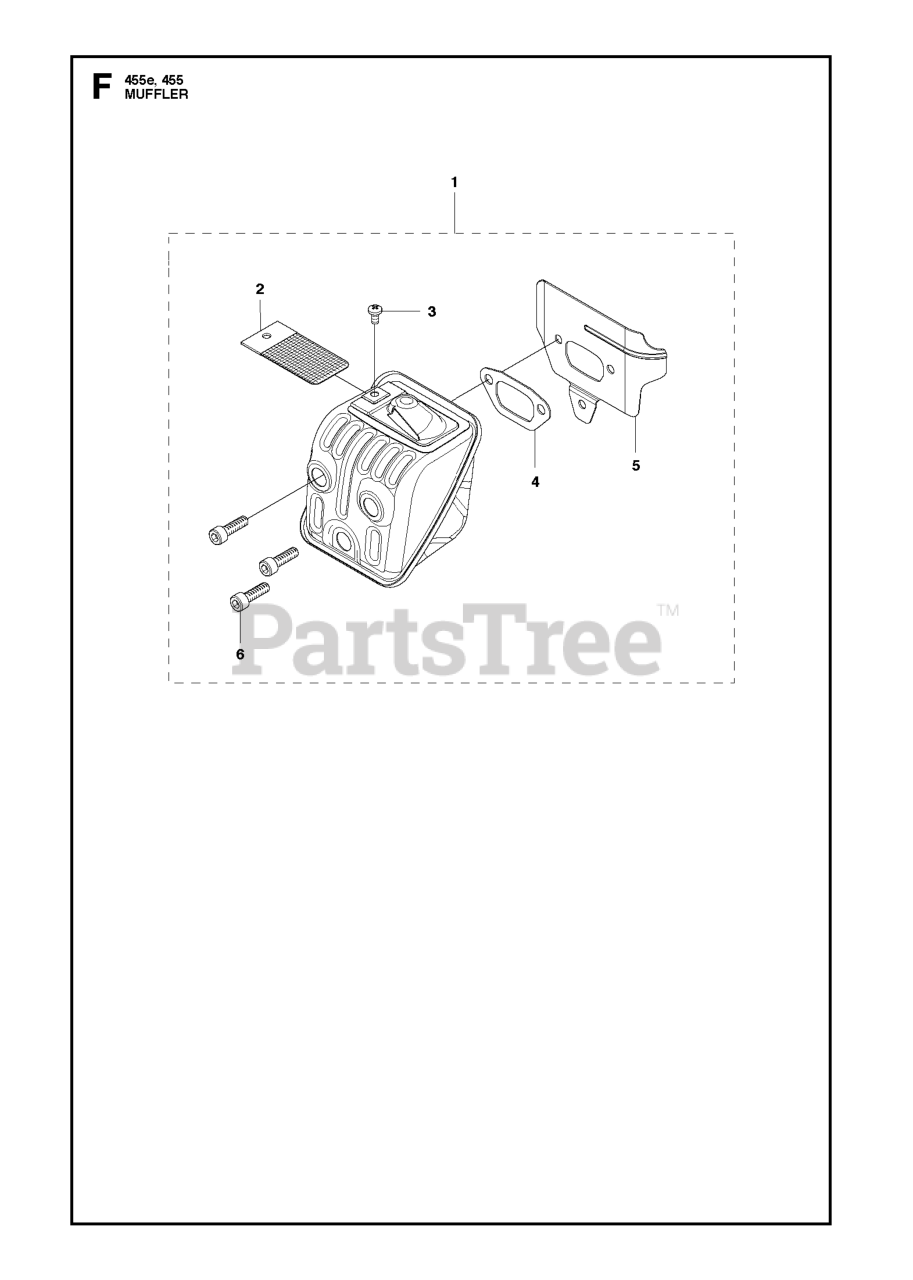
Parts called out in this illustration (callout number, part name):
1	MUFFLER KIT
2	SPARK ARRESTOR SCREEN
5	HEAT DEFLECTOR
6	SCREW MC6S 6X20
